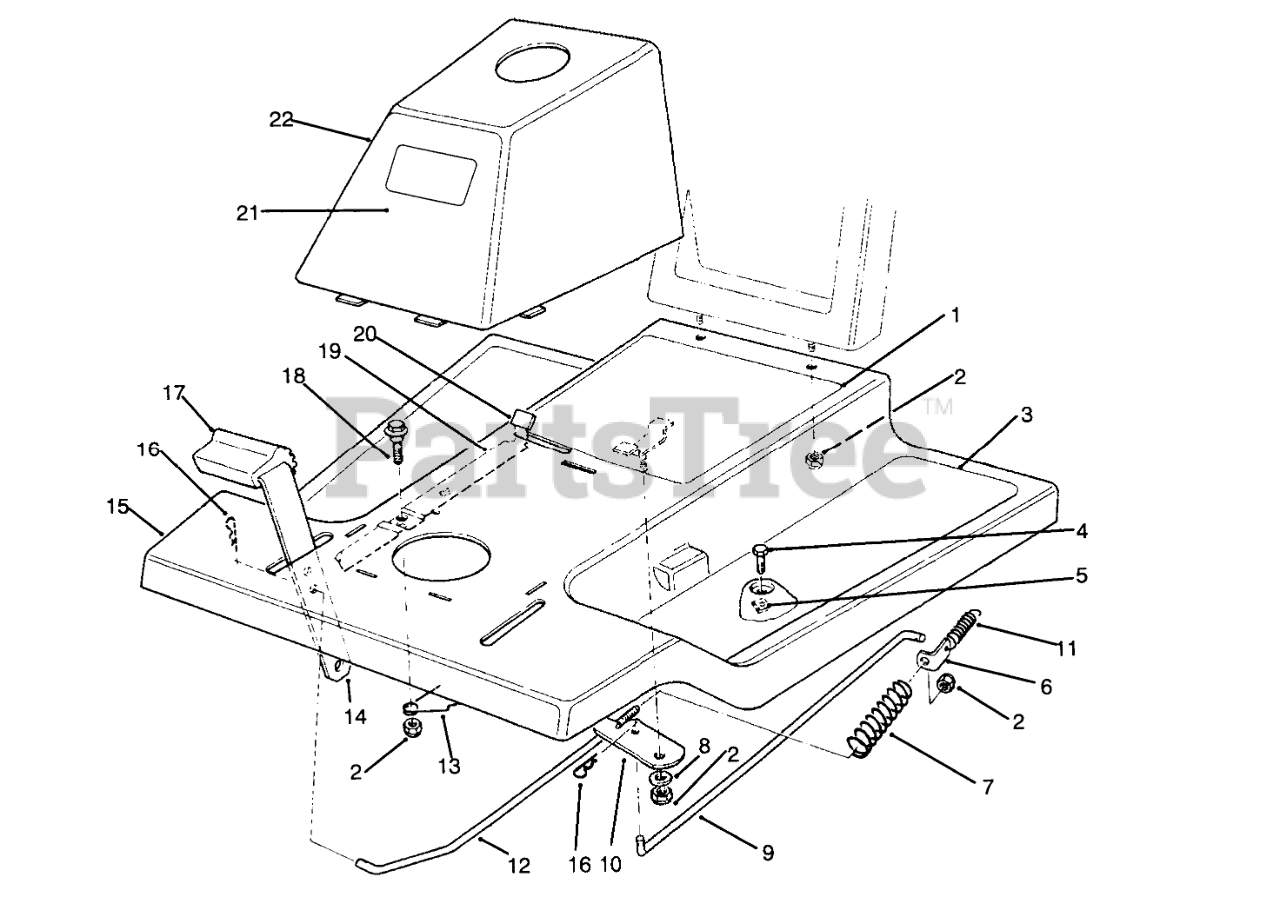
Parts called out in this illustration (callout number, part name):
1	DECAL - INSTRUCTION
2	NUT-LOCK, NI
3	TREAD-FOOT
4	SCREW-HH
5	NUT-TINNERMAN
6	BRACKET-BRAKE RETURN
7	SPRING-TRACTION BRAKE
8	WASHER-PIVOT
9	ROD-TRANS BRAKE
10	LEVER-BRAKE
11	SPRING-IDLER
12	ROD-FRONT BRAKE
13	SPRING-PARKING BRAKE
15	Body W.A.-Front
16	PIN-COTTER
17	PAD-PEDAL
18	SCREW-SHOULDER
19	PARKING BRAKE (BLACK)
20	TIP-PARKING BRAKE
21	DECAL
22	Tower (Incl. Ref. #21)
